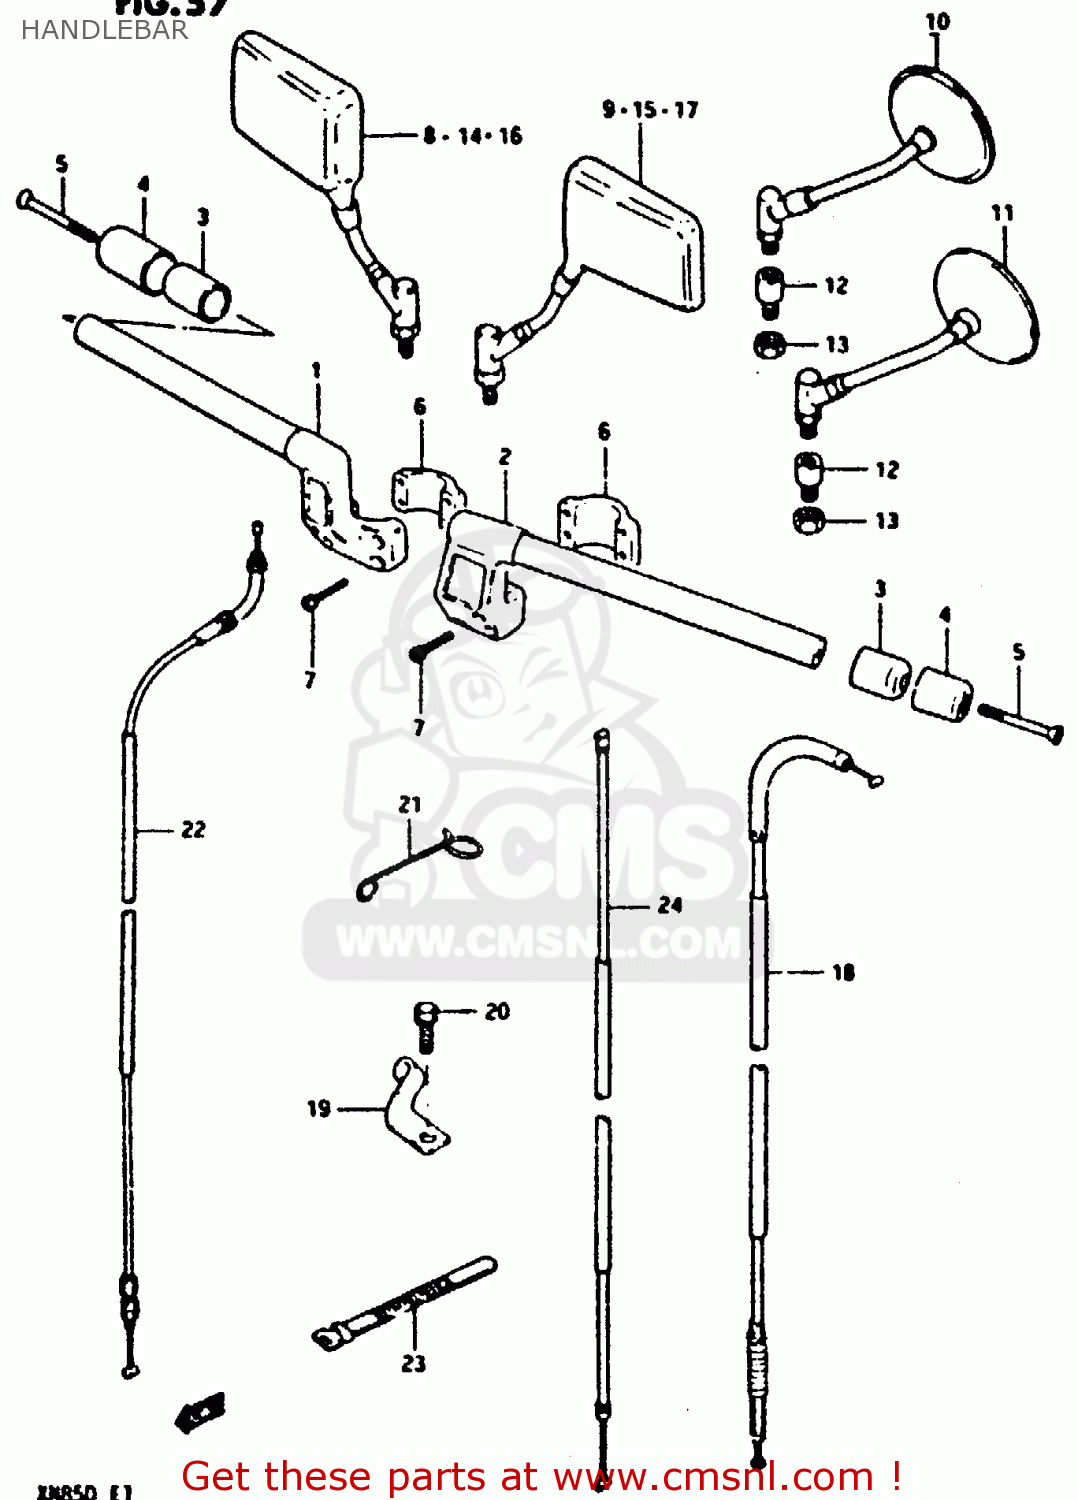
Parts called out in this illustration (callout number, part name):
1	HANDLEBAR,RIGHT
2	HANDLEBAR,LEFT
3	BALANCER,HANDLEBAR
4	CAP,BALANCER
5	SCREW (L:50)
6	HOLDER,HANDLEBAR
7	BOLT
8	MIRROR ASSEMBLY,REAR VIEW
9	MIRROR ASSEMBLY,REAR VIEW
10	MIRROR ASSY,RH
11	MIRROR ASSY,RH
12	CUSHION,REAR VIEW MIRROR
13	NUT
14	MIRROR, REAR VIEW RH
15	MIRROR ASSY,LH
16	MIRROR, REAR VIEW RH
17	MIRROR, REAR VIEW LH
18	CABLE ASSEMBLY,CLUTCH
19	STOPPER,CLUTCH CABLE
20	BOLT
21	GUIDE,CLUTCH CABLE
22	CABLE ASSEMBLY,THROTTLE
23	CLAMP(L:120)
24	CABLE ASSEMBLY,STARTER
